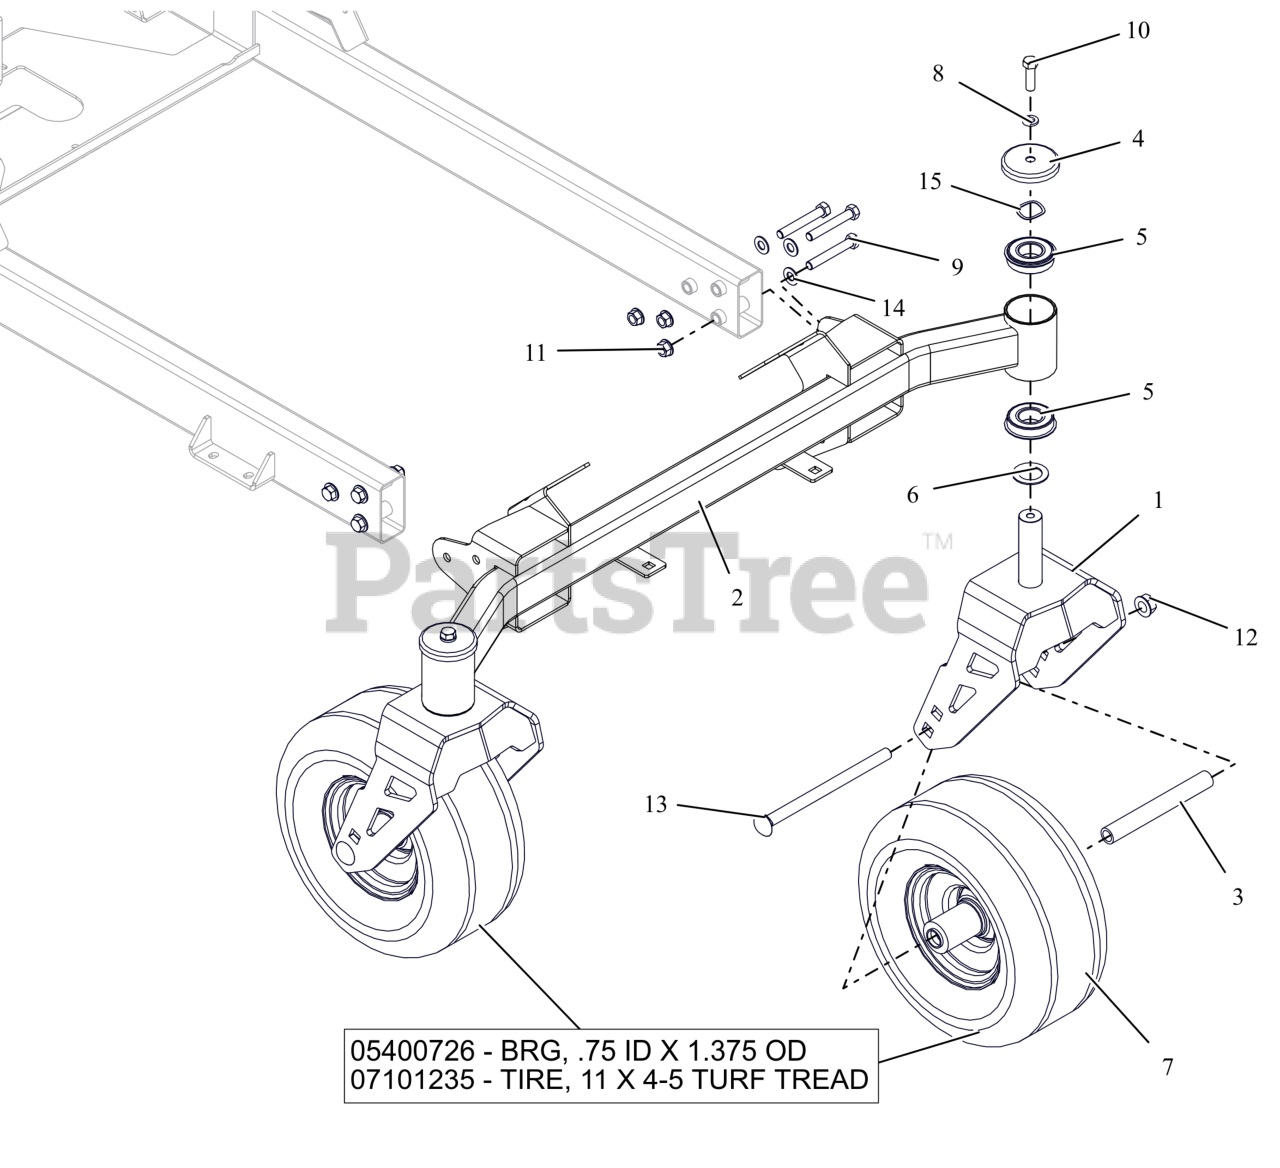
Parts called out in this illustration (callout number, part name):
1	WLDMT, CASTER FORK-XL (ORANGE)
2	WMT-FRONT AXLE-X/XL
3	SPACER, FRONT WHEEL (WIDE 6.0)
4	SHIELD, AXLE BEARING
5	BEARING, BALL -2.000 OD X 1.000 ID X .5625 W/RING
6	WSHR-HRD-THRS 1.007X1.542X.062
7	TIRE/WHEEL ASSY, 11X6-5
8	WSHR,LK-REG .375X.094 ZCC
9	BLT, HEX .38-16X2.50 G8 ZCC
10	BLT, HEX .38-16X1.25 G5 ZCC
11	NUT-LK-TOP-FLG .375-16 GG ZCC
12	NUT-LK-TOP-FLG .500-13 GF ZCC
13	BLT, RHSN .50-13X7.50 G5 ZCC
14	WSHR,FLT-HRD.406X.812X.055 MZC
15	WSHR-WAVE 1.0X1.25X.028 .145FH
15	BRG, .75 ID X 1.375 OD SEALED
15	LAWN TIRE FRONT, 11/6.00-5 SMOOTH
